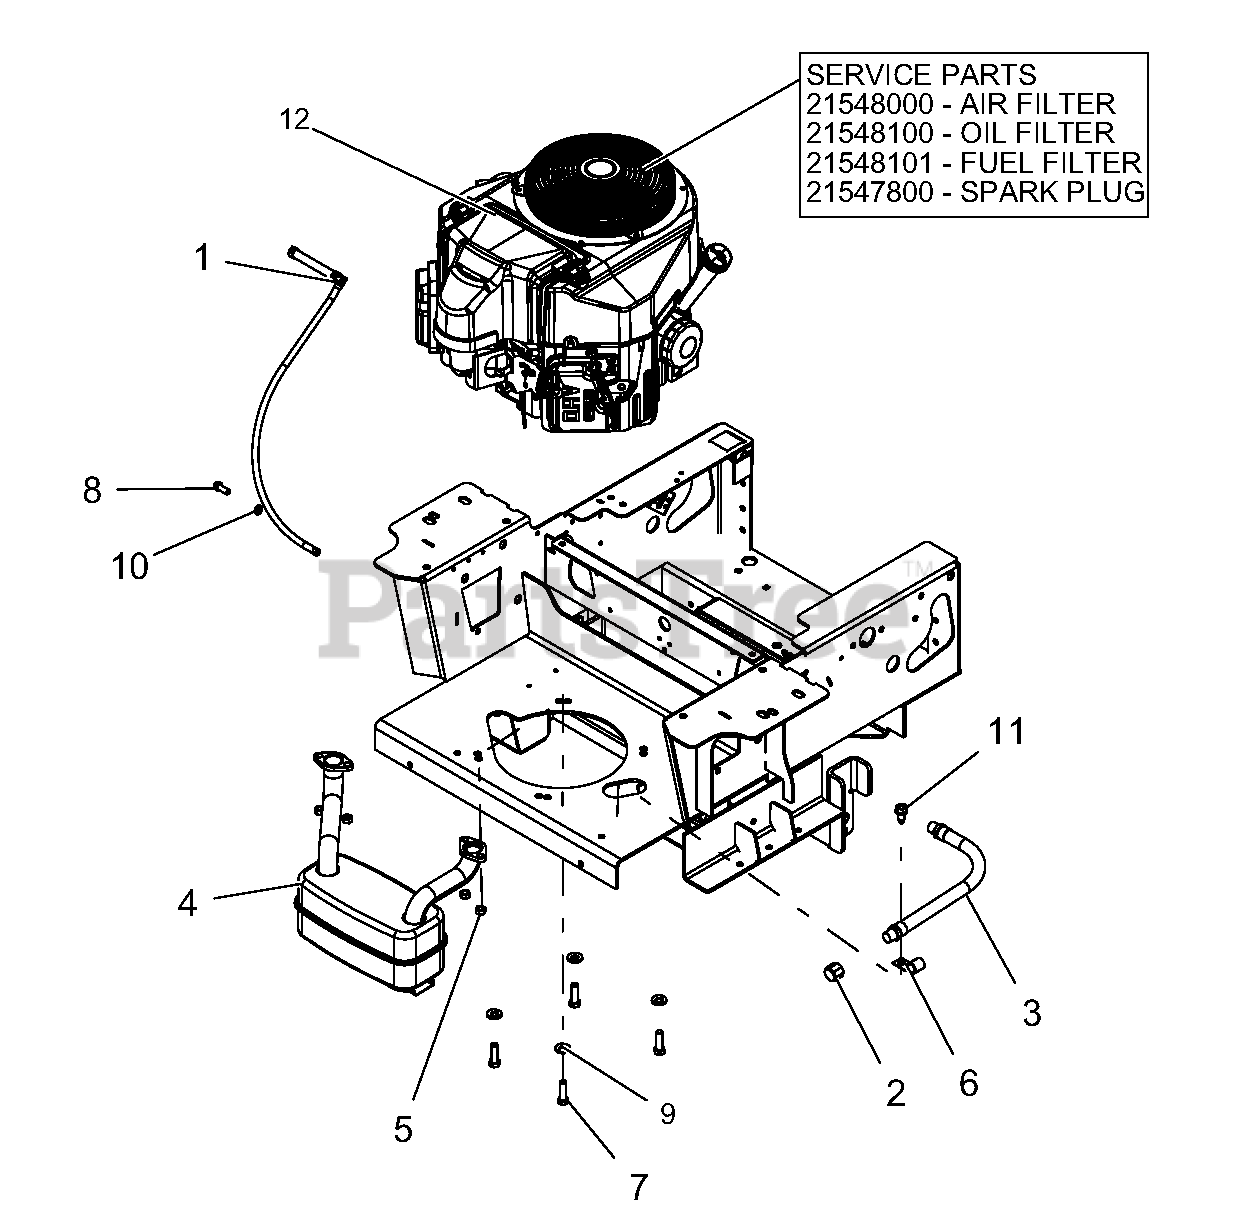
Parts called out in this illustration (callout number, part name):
1	ASM, PT KAW FUEL TANK VENT HOSE
2	PIPE, CAP 3/8 NPT FEMALE
3	HOSE, HYD .38-11-OK M6N0-M6N0
4	MUFFLER, KAWASAKI
5	NUT-LK-TOP M8-1.25 YWZC
7	BLT-HEX .38-16X1.25 GR5 YWZC
8	BLT-HEX M8-1.25X20 YWZC
9	WSHR, 3/8" SPRING DISC
10	WSHR-LK .31X.078 REG YWZC
11	SCR-TAP .38-16X.75 HWH TR YWZ
12	ENGINE, KAWASAKI FS691 (991200, 2021, 204, 205)
13	ENGINE, KAWASAKI FS730 (991202, 206)
